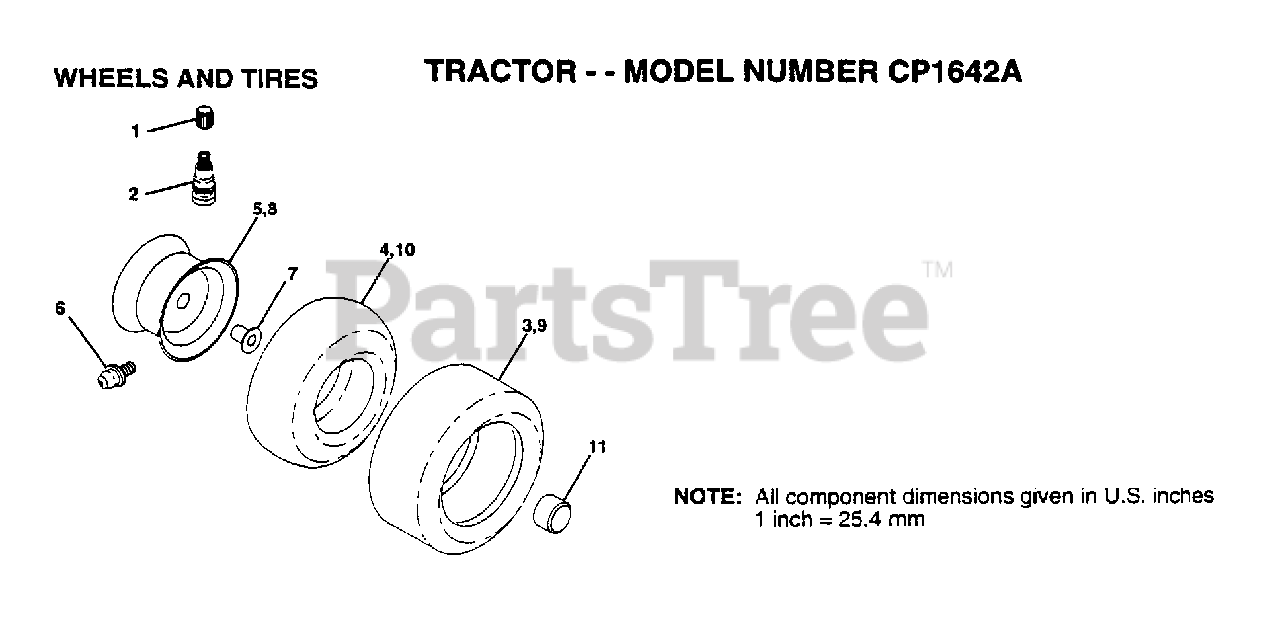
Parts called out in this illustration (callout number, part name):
1	VALVE CAP
2	VALVE STEM LT
4	TUBE.5.3/4.5/6
5	"RIM,FRT T"
6	FITTING LT
7	"FLANGE, BEARING"
8	"RIM 8"""
9	TIRE.20X8-8
10	TUBE.18X9.5-8
11	HUB CAP
